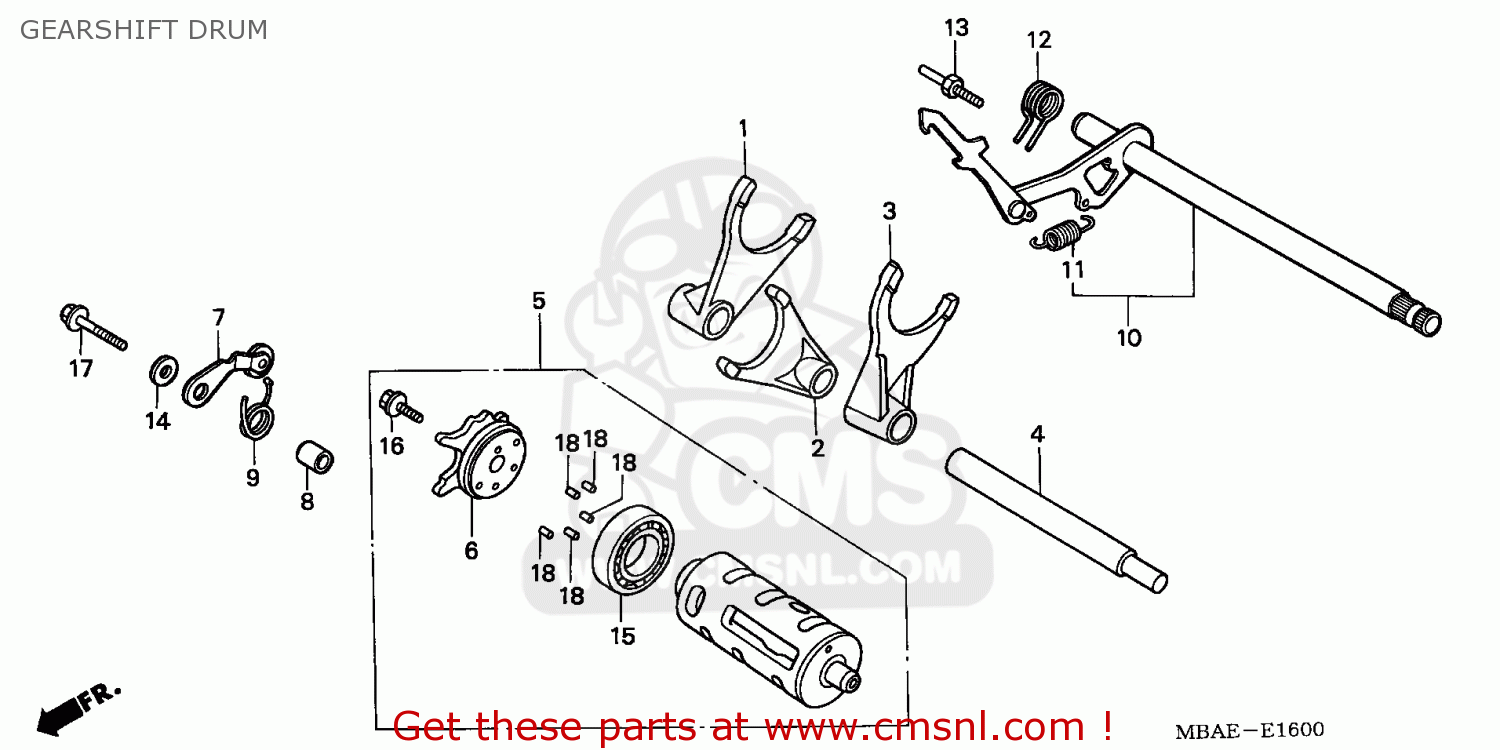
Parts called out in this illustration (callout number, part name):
1	FORK,R GEAR SHIFT
2	FORK,C GEAR SHIFT
3	FORK,L GEAR SHIFT
4	SHAFT,SHIFT FORK
5	DRUM COMP.,GEARSH
6	PLATE COMP.,CAM
7	STOPPER,DRUM
8	COLLAR,DRUM STPR.
9	SPRING,SHIFT DRUM
10	ARM COMP,GEAR SHI
11	SPRING, SHIFT
12	SPG,SHIFT RETURN
13	PIN, SHIFT RETURN
14	WASHER, 6X2.3
15	B/BRG RAD N/COM
16	BOLT FLANGE 6X18
17	BOLT,FLANGE,6X28
18	ROLLER,4X11.8
